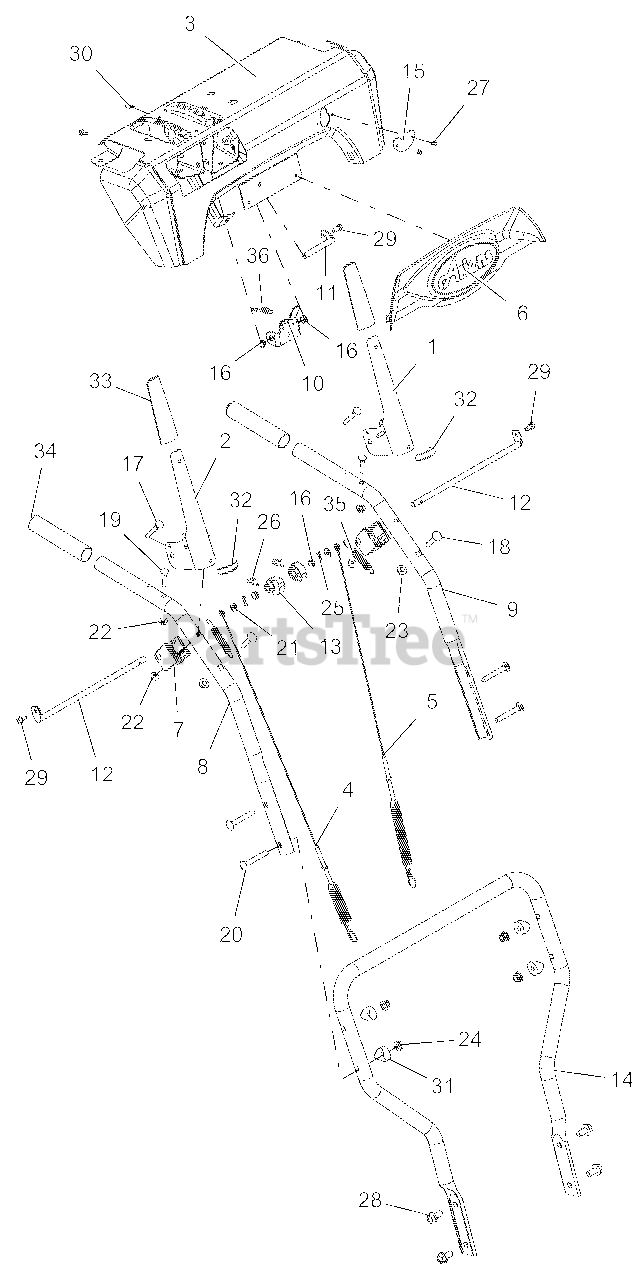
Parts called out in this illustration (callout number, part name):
1	LEVER, CLUTCH-LH
2	LEVER, CLUTCH-RH
3	CONTROL PANEL W/DECAL ID,AT
4	CABLE, AUGER (DELUXE & PRO)
5	CABLE, UPPER TRACTION
6	DASH BEZEL, ARIENS LOGO - PRO
7	BLOCK, CLUTCH PADDLE
8	HANDLEBAR, UPPER - RH
9	HANDLEBAR, UPPER - LH
10	BRACKET, INTERLOCK ARM
11	ROD, PIVOT - INTERLOCK
12	ROD, PADDLE MOUNT - PRO
13	CAM, INTERLOCK
14	HANDLEBAR, LOWER - DELUXE
15	COVER, DASH BRKT, ID
16	BUSHING, POLYLINER-.38 SNAPIN
17	BLT-RDHDXLSQNK .25-20X2.0 G5YZ
18	@BLT-RDHDSQNK .31-18X1.50 G5YZ
19	BLT-RDHDXLSQNK.25-20X1.25 G5ZC
20	@BLT-RDHDSQNK .31-18X2.25 G5YZ
21	@WSHR-FL-STL.281X.62X.065 YWZC
22	@NUT-LK-CTR-FLG .25-20 YWZC
23	@NUT-LK-TOP-FLG .31-18 YWZC
24	@NUT-LK-NYL-FLG .31-18 YWZC
25	PIN-HAIR INT .06X.18X.77
26	PIN, SPRING CLIP
27	RVT-POP #43 .125X.313 STL ZINC
28	BLT-SERHFWH .38-16X.75 YWZC
29	SCR-TAP .25-20X.50 HWH TR YWZ
30	SCR-TAP #10X.50 BOSS INDHXHD
31	SPACER, HANDLEBAR
32	EDGING, CLUTCH PADDLE - 2.00"
33	CLUTCH PADDLE SLEEVE - GRAY
34	HANDLE GRIP
35	SPRING, EXTENSION
36	SPRING-EXT .047X.438X1.45
